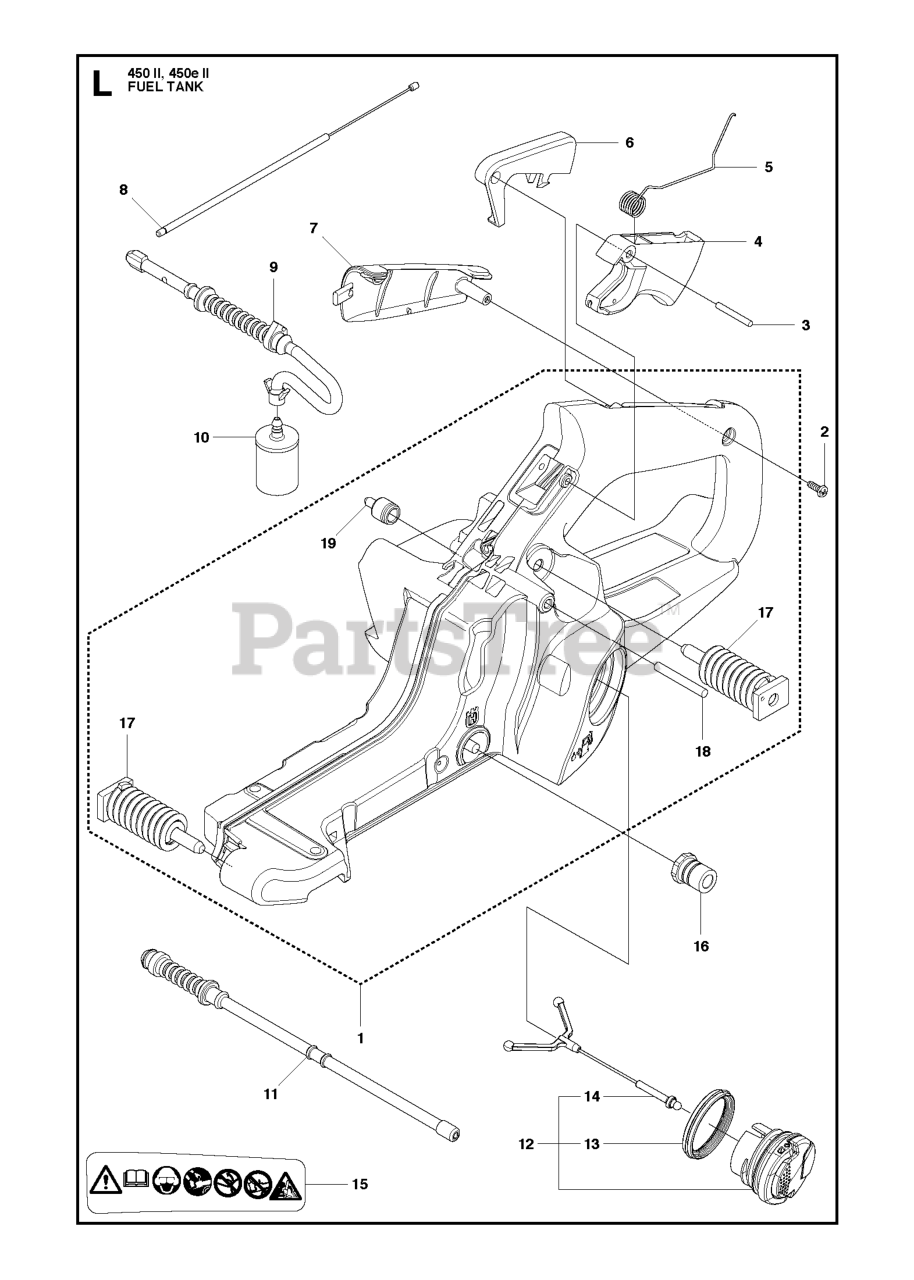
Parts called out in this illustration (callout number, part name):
1	ASSY FUEL TANK
4	THROTTLE TRIGGER
6	THROTTLE LOCKOUT
7	HANDLE INSERT
8	THROTTLE CABLE ASSY
10	RP FUEL FILTER
11	RETURN HOSE
12	TANK CAP ASSY
16	LATERAL SUPPORT
17	ANTI VIBRATIONS ELEMENT
18	GROOVED PIN
19	FUEL TANK VENT
